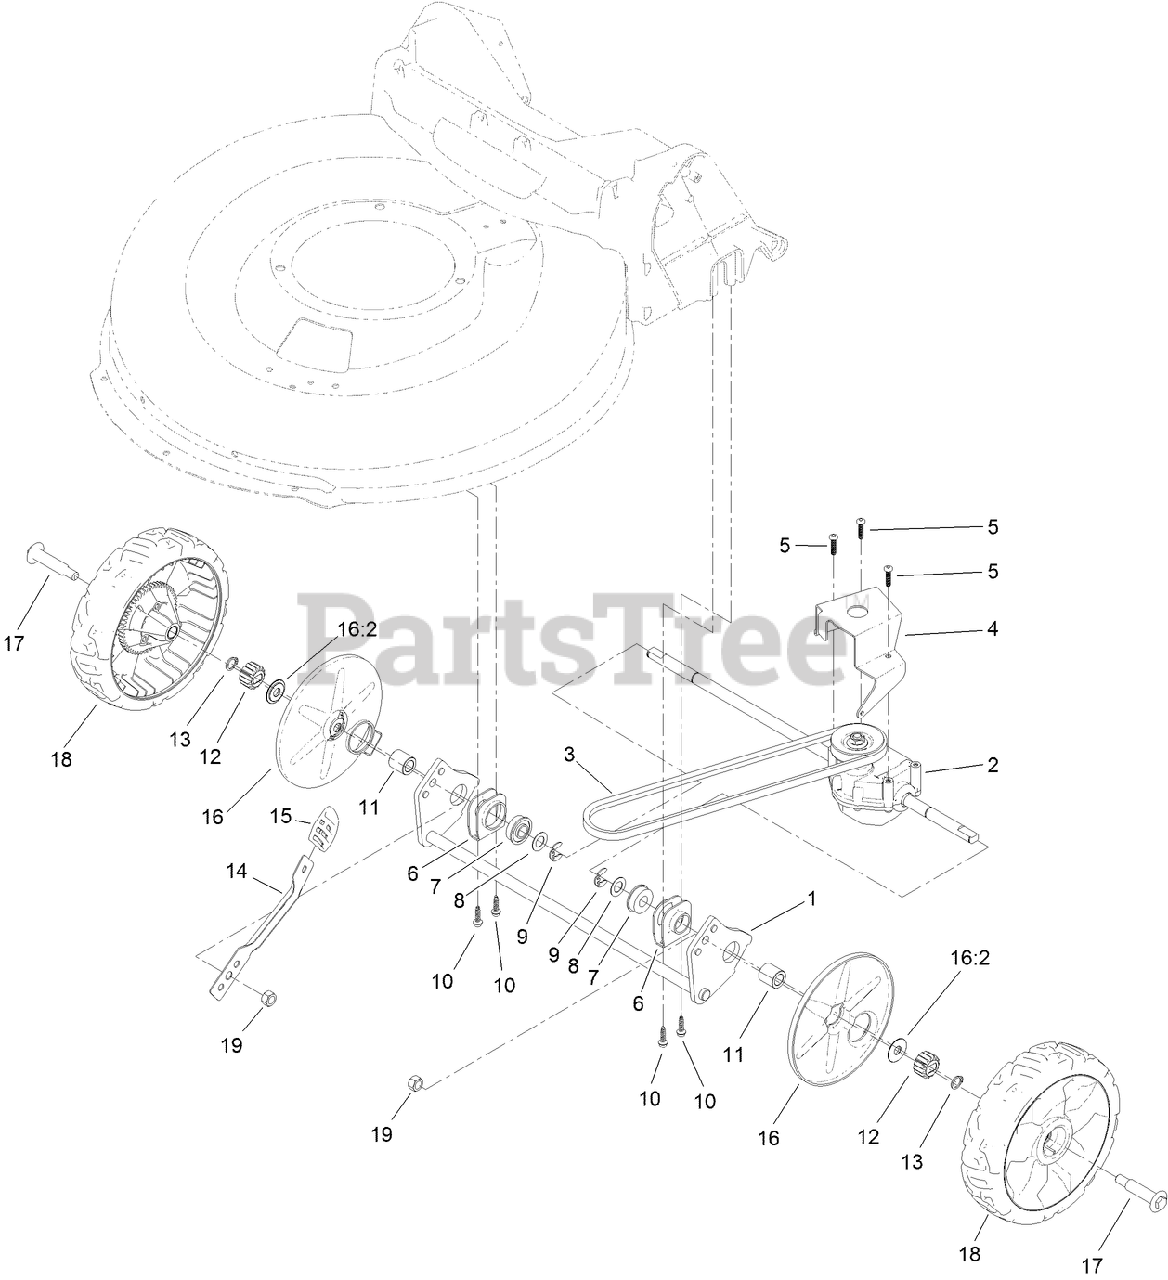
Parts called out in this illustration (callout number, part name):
2	TRANSMISSION
4	BRACKET-TRANSMISSION
5	SCREW-PLASTITE
6	RETAINER-BEARING
7	BEARING-BALL
8	WASHER-PLAIN
9	RING-RETAINING,CLIP
10	SCREW-HWH
11	BUSHING-SLEEVE
12	GEAR-PINION, 15T
13	RING-RETAINING
14	ARM-SPRING
15	KNOB-LEVER, HOC
16	WHEEL COVER ASM
16:2	WASHER-STEPPED
17	BOLT-SHOULDER
19	NUT-HEX
